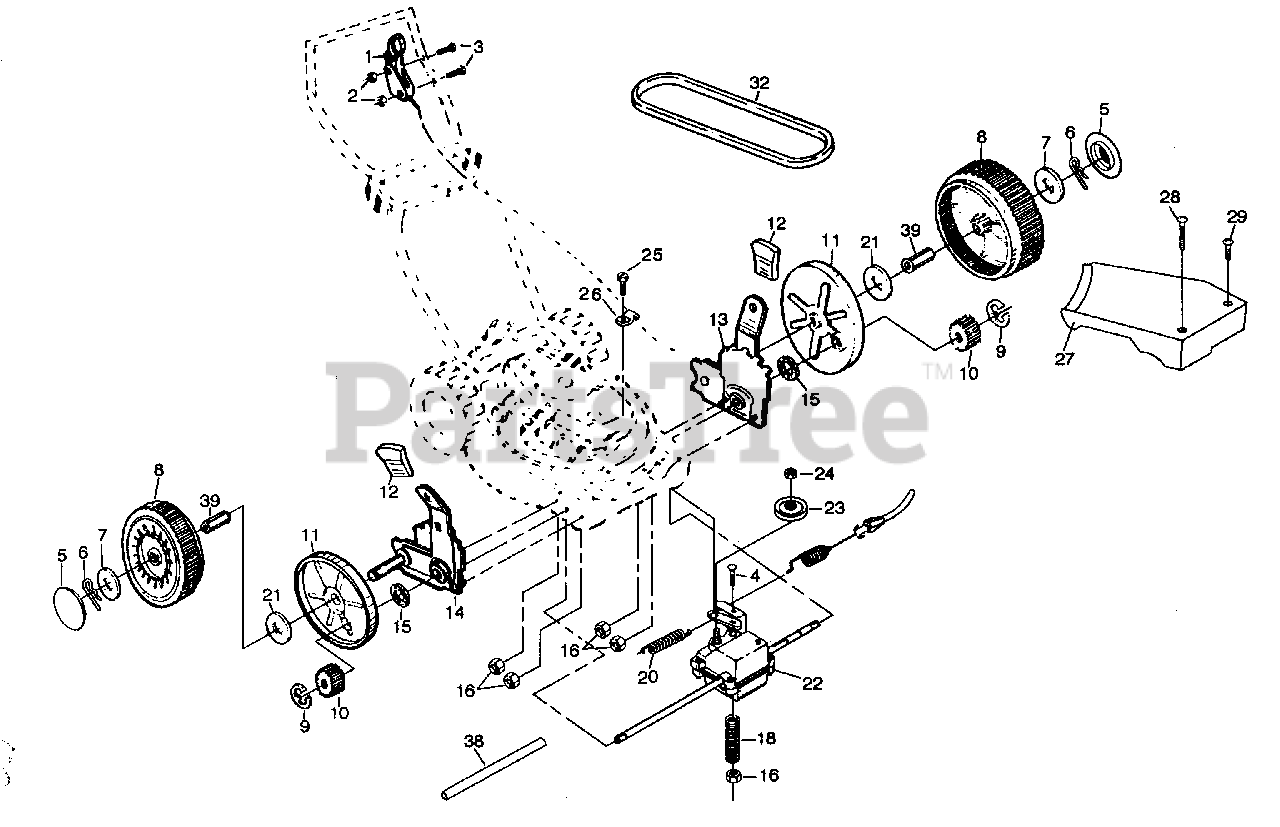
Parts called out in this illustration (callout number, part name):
1	Drive Control (AYP part number)
2	Locknut #10-24 (AYP part number)
3	Pan Head Machine Screw #10-24 x 2 (AYP part number)
4	Carriage Bolt 1/4-20 x 2 (AYP part number)
5	Hubcap (AYP part number)
6	Retainer Clip (AYP part number)
7	Washer (AYP part number)
8	Wheel & Tire Assembly (AYP part number)
9	E-ring (AYP part number)
11	Dust Cover
12	Selector Knob
13	Wheel Adjuster Assembly (Left) (AYP part number)
14	Wheel Adjuster Assembly (Right) (AYP part number)
15	Felt Washer (AYP part number)
16	Locknut (AYP part number)
18	Spring (AYP part number)
21	Washer 1/2 x 1-1/2 x .134 (AYP part number)
22	Gear Case Assembly (AYP part number)
23	Drive Pulley (AYP part number)
24	Locknut (AYP part number)
25	Hex Head Screw # 10-2 (AYP part number)
26	Guide Clip (AYP part number)
27	Drive Cover
28	Pan Head Tapping Screw #10-24 x 2-3/4 (AYP part number)
29	Pan Head Tapping Screw #10-24 x 1-3/4 (AYP part number)
32	V-Belt
38	Drive Shaft Cover (AYP part number)
39	Wheel Bushing (AYP part number)
